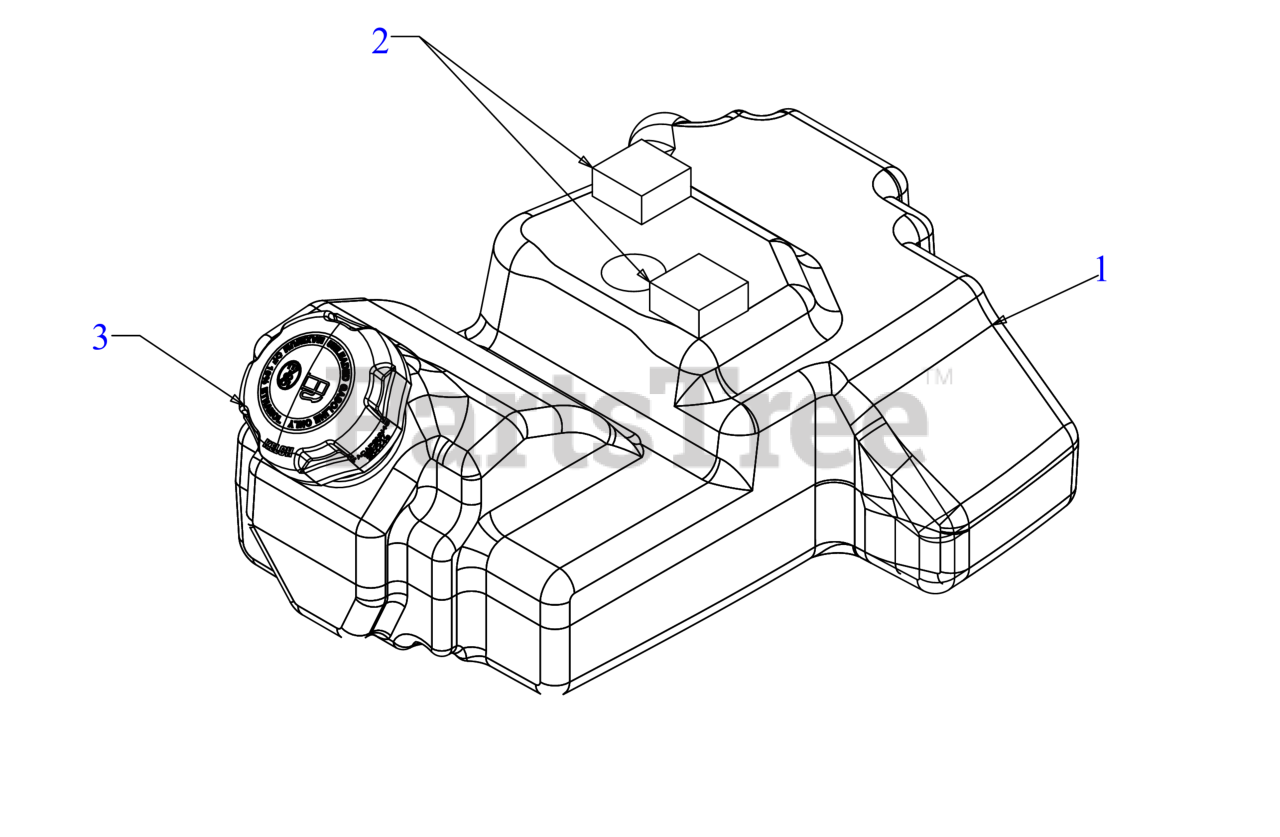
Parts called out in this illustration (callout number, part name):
1	FUEL TANK ASSEMBLY 1.3 GAL
2	FOAM-1.25SQ x .62T
3	FUEL CAP W/TETHER
